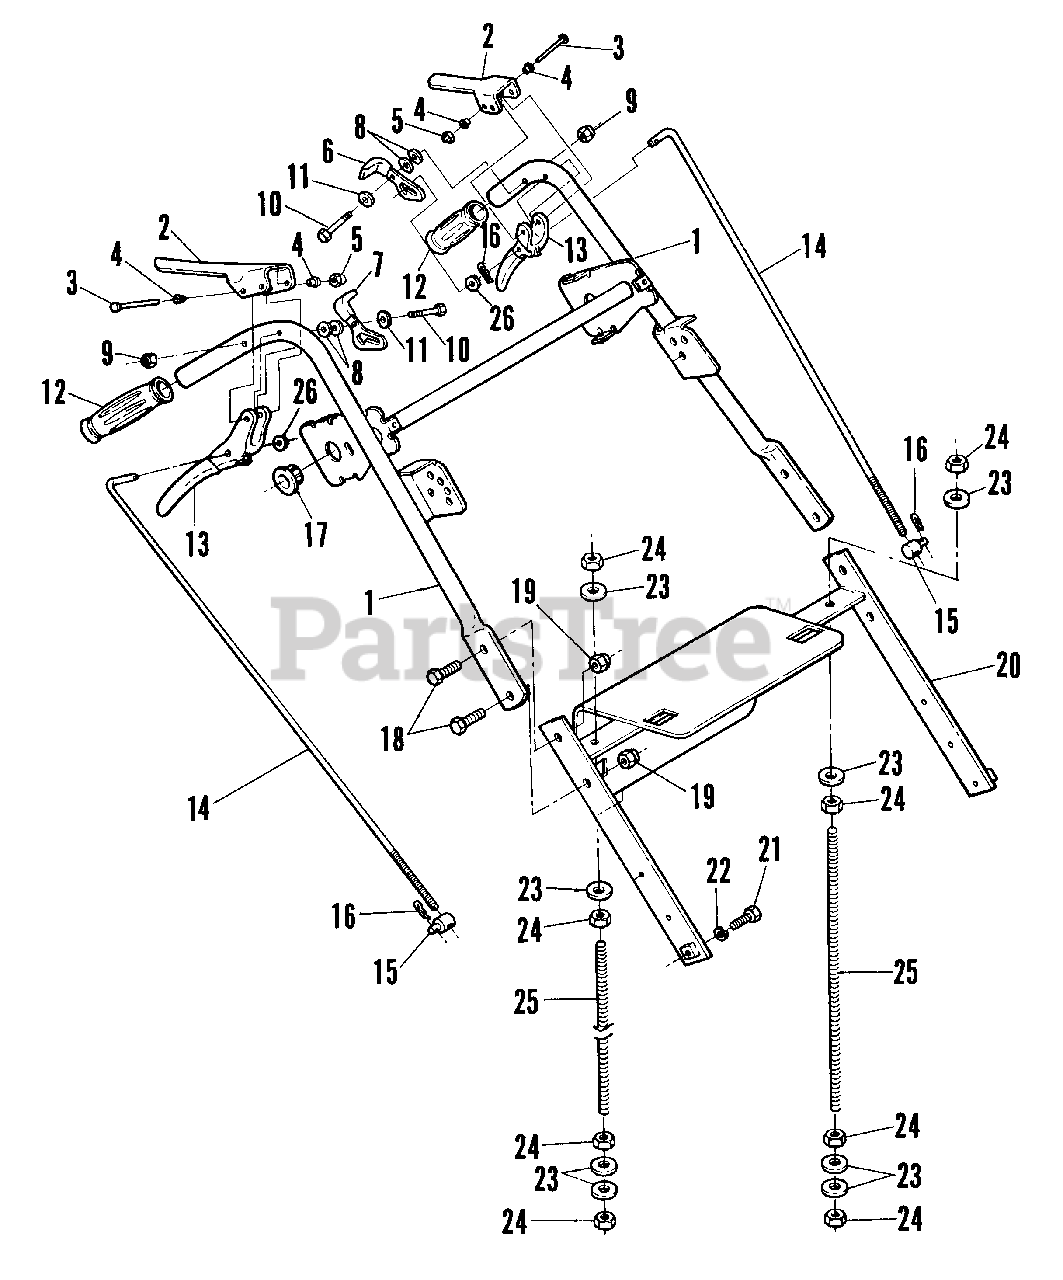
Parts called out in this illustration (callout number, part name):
1	HANDLE, Upper Weldment w/Decals
2	LEVER, Operator Presence w/Grip
3	PIN, Clevis
4	BUSHING
5	NUT, Push
6	LATCH, Thumb w/Grip L.H.
7	LATCH, Thumb w/Grip R.H.
8	WASHER, Flat 1/4" SAE
9	NUT, Prevailing Torque 1/4 - 20
10	SCREW, Hex Head Cap 1/4 - 20 x 1 3/4
11	WASHER, Spring Wave 1/4" Dia.
12	GRIP, Handle
13	LEVER, Traction w/Grip
14	ROD, Traction
15	SWIVEL, Long
16	COTTER, Hairpin No. 2
17	BUSHING, Snap
18	SCREW, Hex Head Cap 3/8 - 16 x 1
19	NUT, Nyloc Hex 3/8 - 16
20	HANDLE, Lower
21	SCREW, Hex Hed Cap 3/8 - 16 x 1 1/4
22	WASHER, Lock 3/8
23	WASHER, Lock 1/2"
24	NUT, Regular Hex 1/2 - 13
25	BRACE, Handle
26	WASHER, Flat 5/16 Std.
